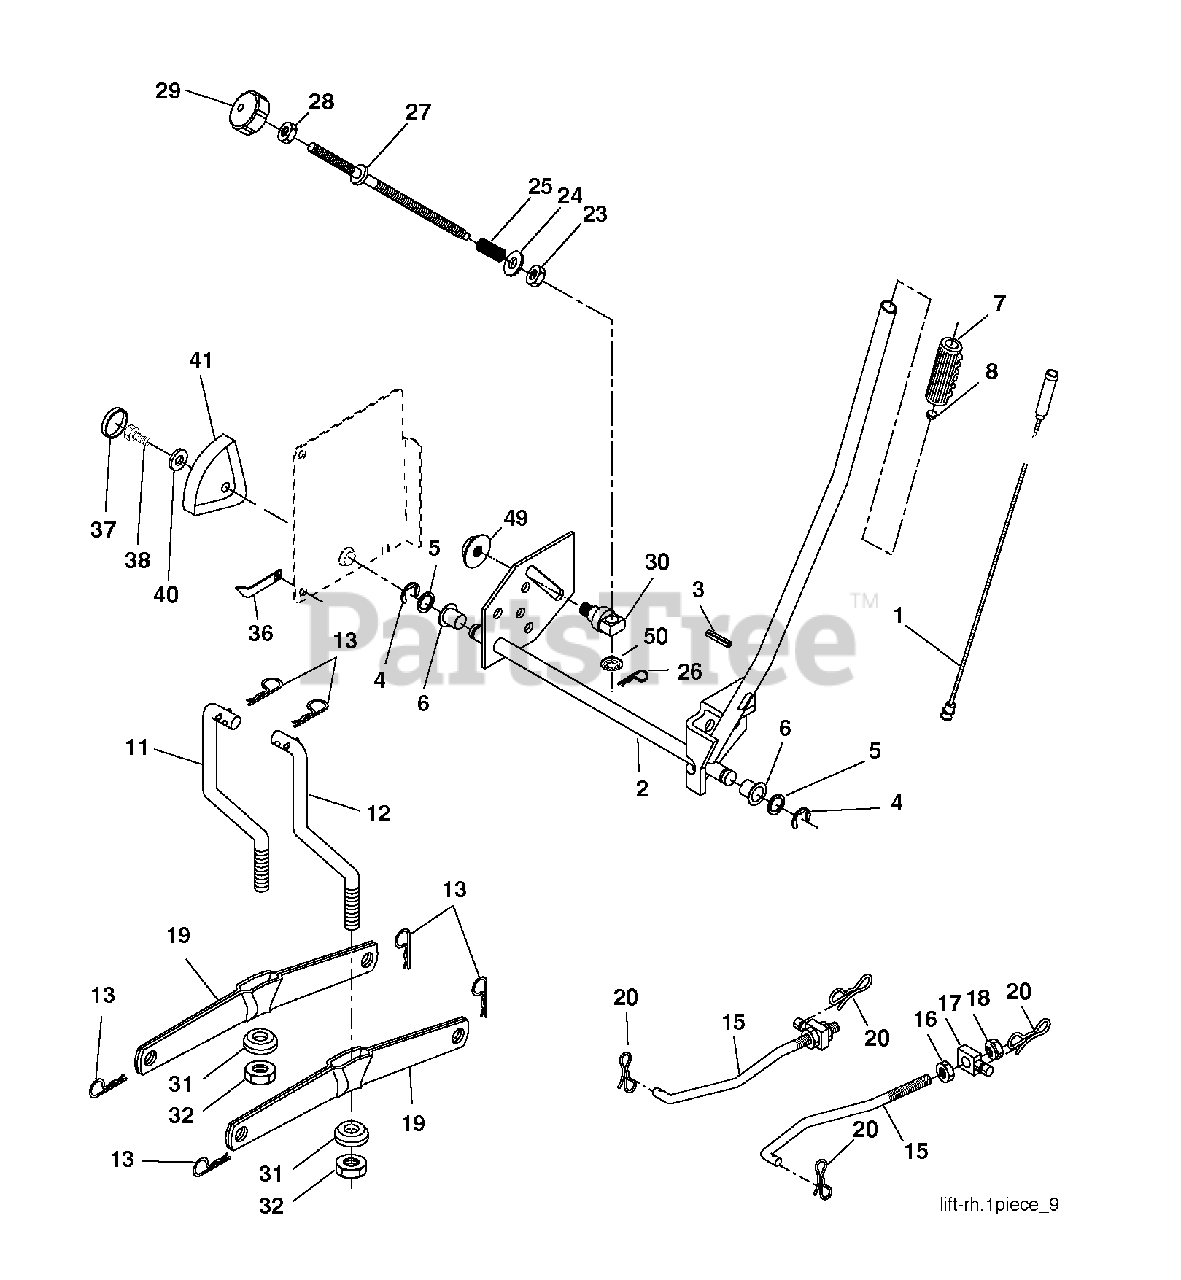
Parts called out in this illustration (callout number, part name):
1	PLUNGER.ASM.LIFT.LVR.BLK.17.32
2	SHAFT ASM R HANDLE
3	PIN GROOVE
4	RETAINING RING LT
6	BEARING.NYLON
7	GRIP HANDLE
8	PLUNGER BUT KIT
11	LINK
12	LINK
13	RETAINER-SPRNG RB
15	LINK.SUSPENSION.FRONT
16	NUT
18	NUT
19	ARM.REAR.SUSPENSION
20	PIN.COTTER.7/16.BOW TI
25	SPRING**
26	RETAINER CLIP
27	ROD ADJ LIFT
28	NUT
29	KNOB INF 3/8-16
31	BEARING.PIVOT.LIFT
32	NUT CROWNLOCK 3/8-24
36	POINTER, HEIGHT INDICATOR
37	PLUG,HOLE
38	SCREW 5/16-18X1
41	HEIGHT INDICATOR
49	NUT
50	NUT PUSH M
